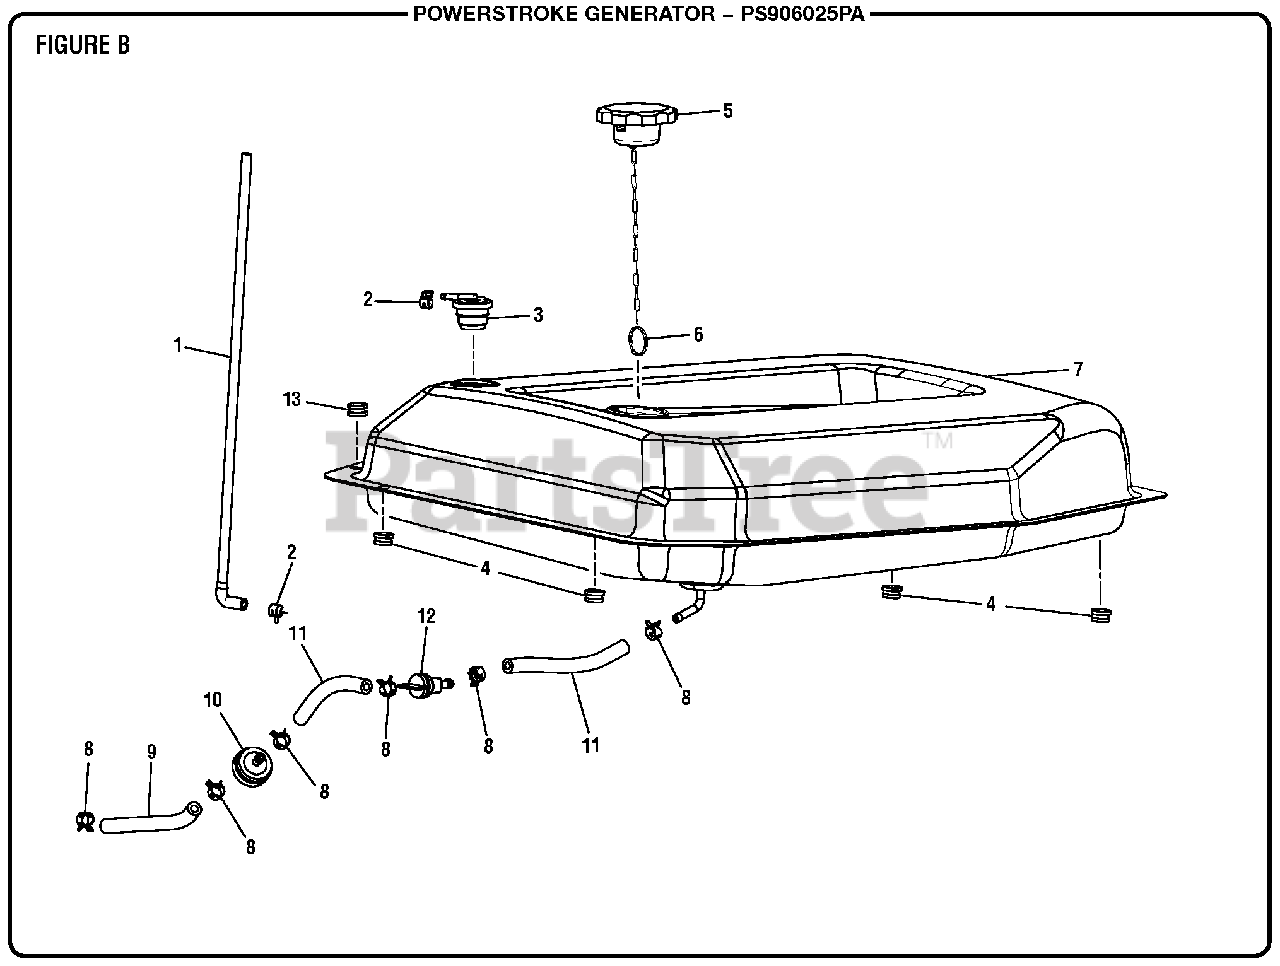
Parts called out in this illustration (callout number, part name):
1	Vapor Hose
2	Clamp (7/16 in.)
3	Fuel Tank Vapor Vent
6	Ring Clip
7	Fuel Tank
8	Clamp (1/2 in.)
9	Fuel Hose
10	Fuel Filter
11	Fuel Hose
12	Fuel Shut Off Valve
